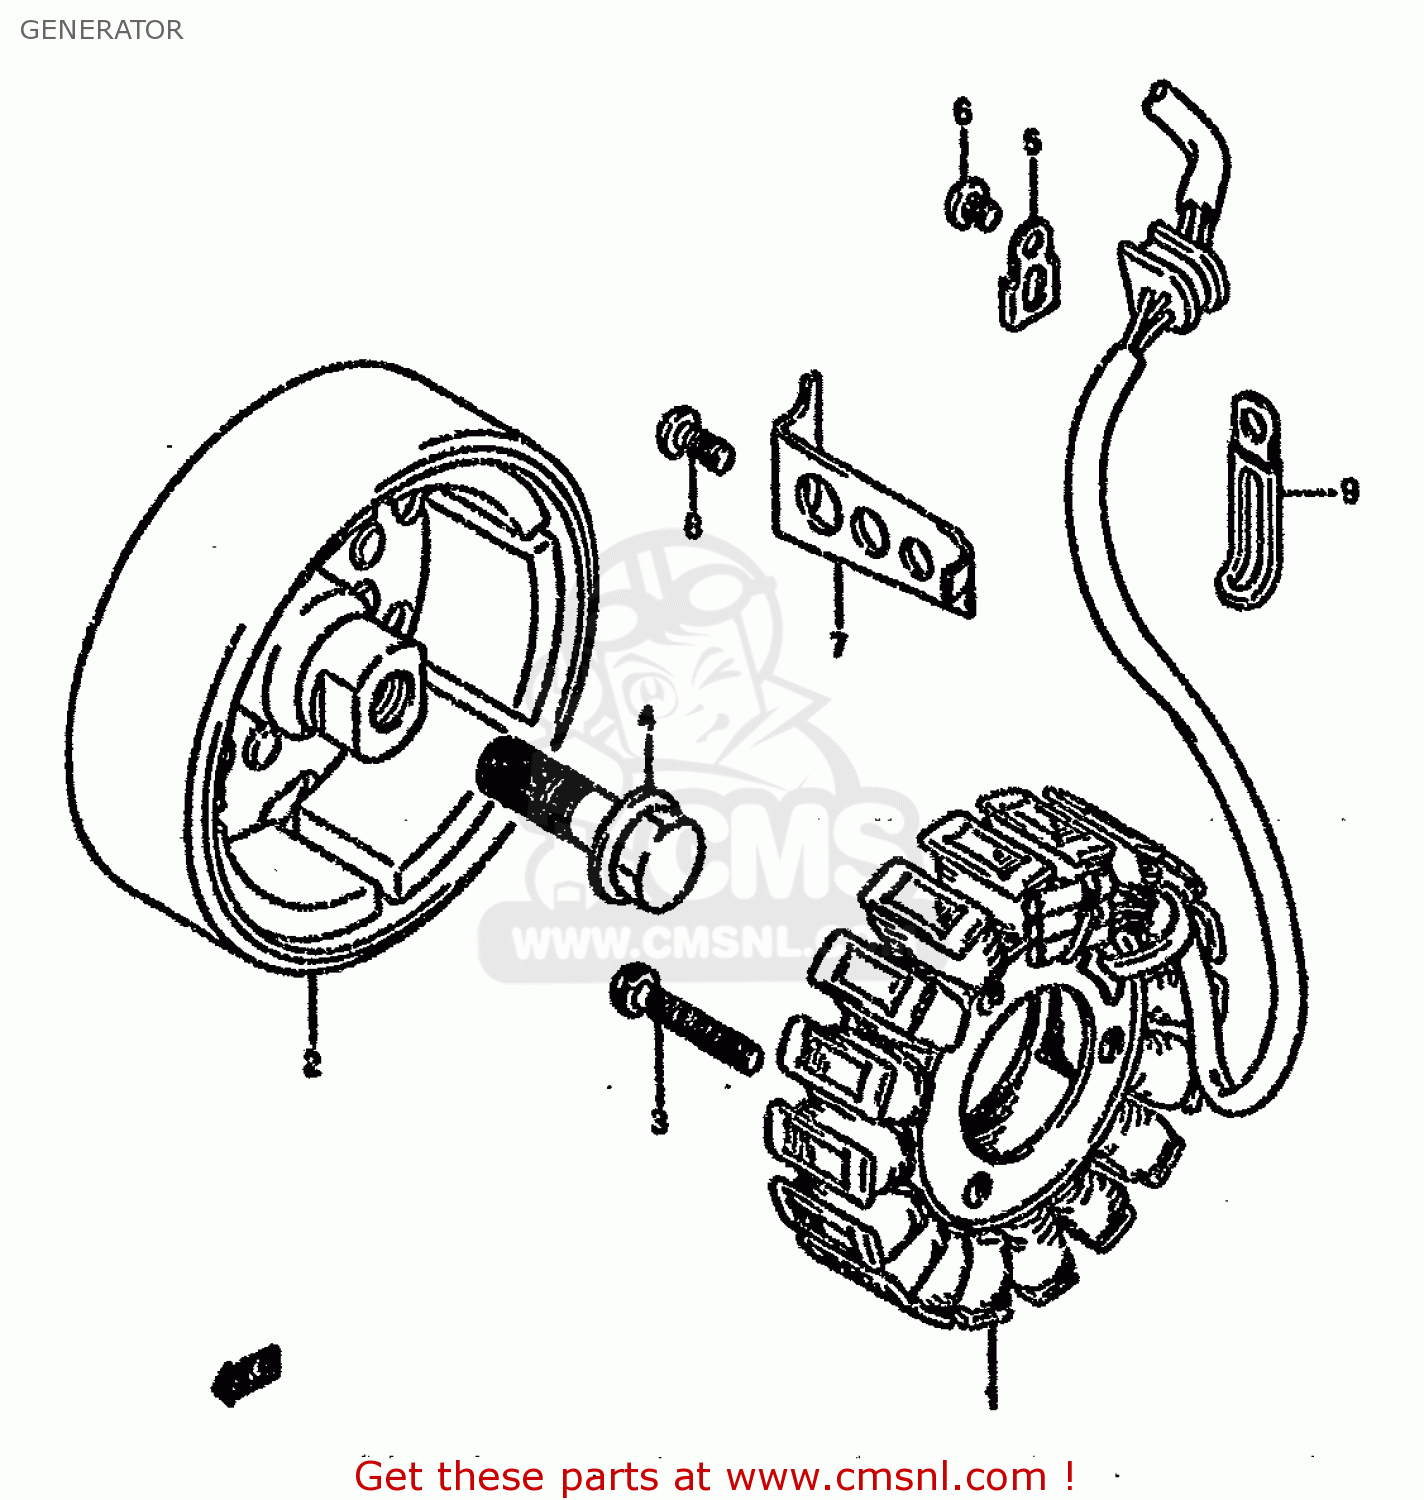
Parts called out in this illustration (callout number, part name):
1	STARTER ASSY
2	ROTOR ASSY
3	SCREW
4	BOLT(12X40)
5	CLAMP,GENERATOR LEAD WIRE
6	SCREW
7	CLAMP,GENERATOR LEAD WIRE
8	SCREW
9	CLAMP
